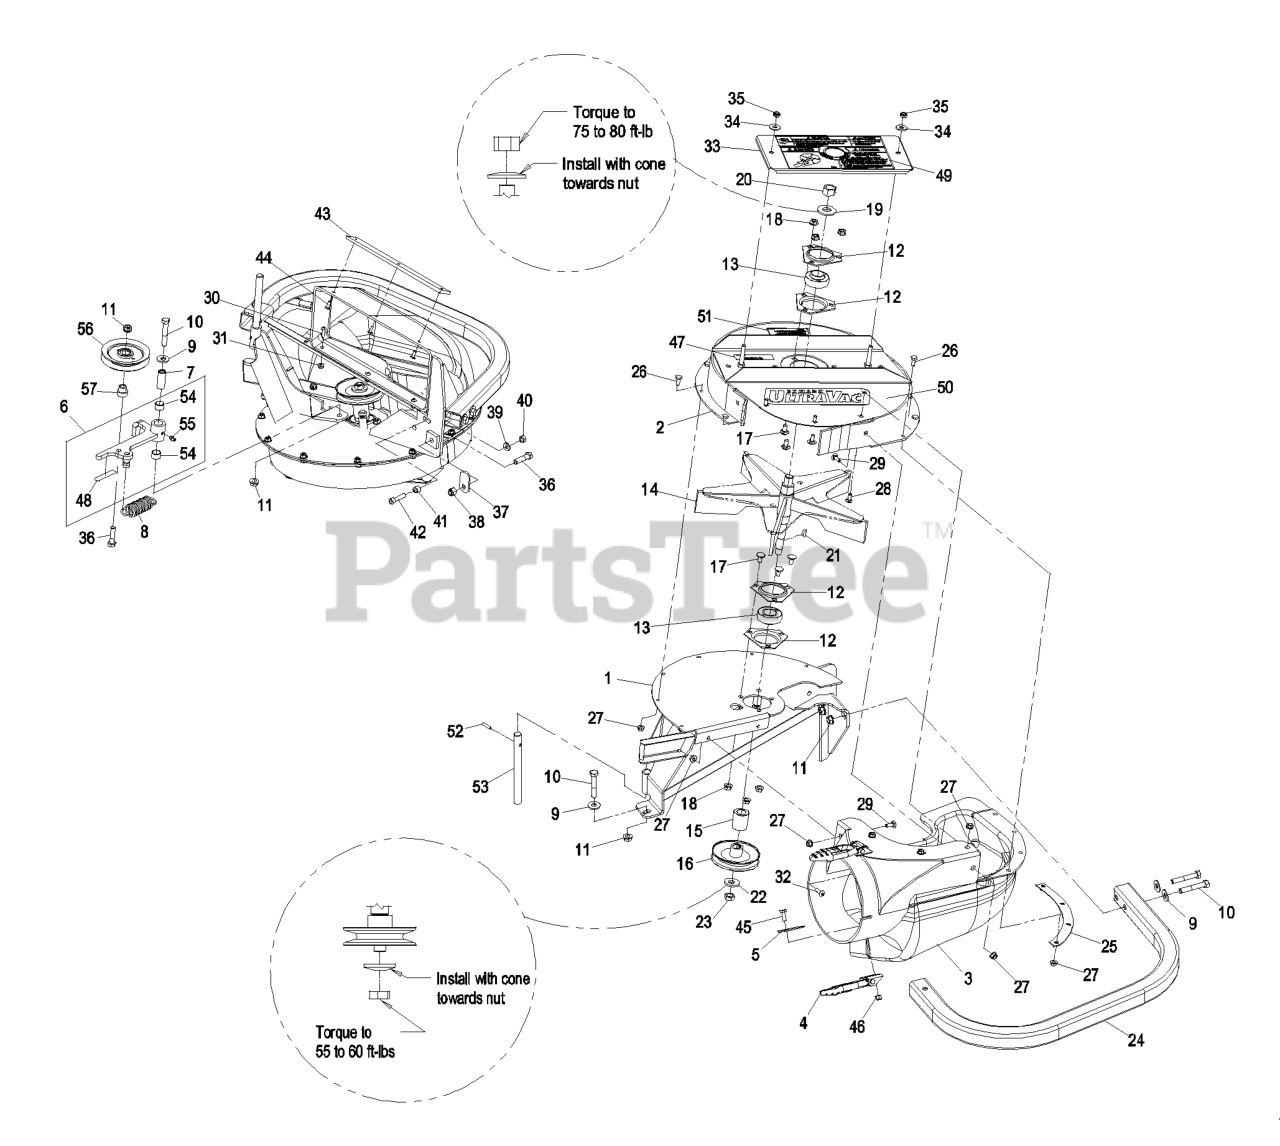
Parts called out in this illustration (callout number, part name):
1	WLD,FRAME LG BLOWER
2	ASM, UPPER HSG
3	ASM,BLOWER CHUTE LZ
4	LATCH-RUBBER
5	PLATE-BACKING
6	ASM, IDLER ARM - SERVICE
7	BUSHING
8	SPRING-IDLER
9	WASHER-FLAT
10	SCREW-HH
11	NUT-HHF, WHIZ
12	HOUSING-FLANGE
13	BEARING
14	IMPELLER
16	SHEAVE
17	SCREW-CARR
19	WASHER-SPRING
20	NUT-HEX
21	KEY-WOODRUFF
22	WASHER-SPRING
23	NUT-JAM
25	PLATE-BACKING, BLOWER
26	SCREW-HH
28	SCREW-CARR
29	BOLT-CARR
30	SCREW-HEAD, TRUSS
33	ASM, BEARING COVER
34	WASHER-FLAT
35	NUT-LOCK, NI
36	SCREW-HH
37	LATCH-CATCHER, GRASS
38	NUT-LOCK, NI
39	WASHER-SPRING
40	NUT-HEX
41	BUSHING, LOCATOR
42	SCREW-HSH
43	PLATE,REINFORCEMENT LARGE
44	RIVET-BLIND
45	SCREW-HH
46	NUT-LOCK, NI
47	DECAL-COVER, MISSING
48	DECAL-WARNING
49	DECAL-WARNING, BLOWER
50	DECAL, ULTRA VAC
51	DECAL,WEIGHT
52	PIN-ROLL
53	SHAFT-CATCHER, GRASS
54	BUSHING
55	FITTING-GREASE
57	HUB,SPACER
